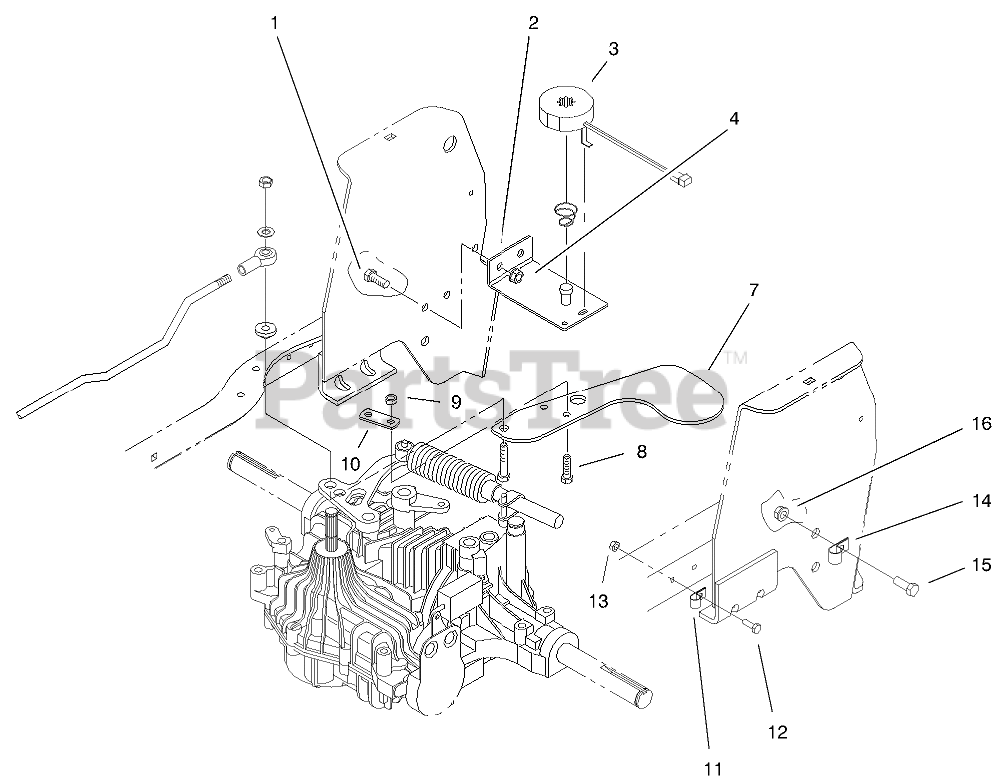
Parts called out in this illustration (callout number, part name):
1	SCREW-HH
2	BRACKET - CRUISE, WA
3	ASM - MAGNET
4	NUT-LOCK, NI
7	ARM - CRUISE
8	SCREW-HH
9	NUT-LOCK, NI
10	CLAMP - CRUISE
11	CLAMP-R
12	SCREW-HH
13	NUT-LOCK, NI
14	ARDEN PART NUMBER CFV-0713
15	SCREW-HH
16	NUT-LOCK, NI
